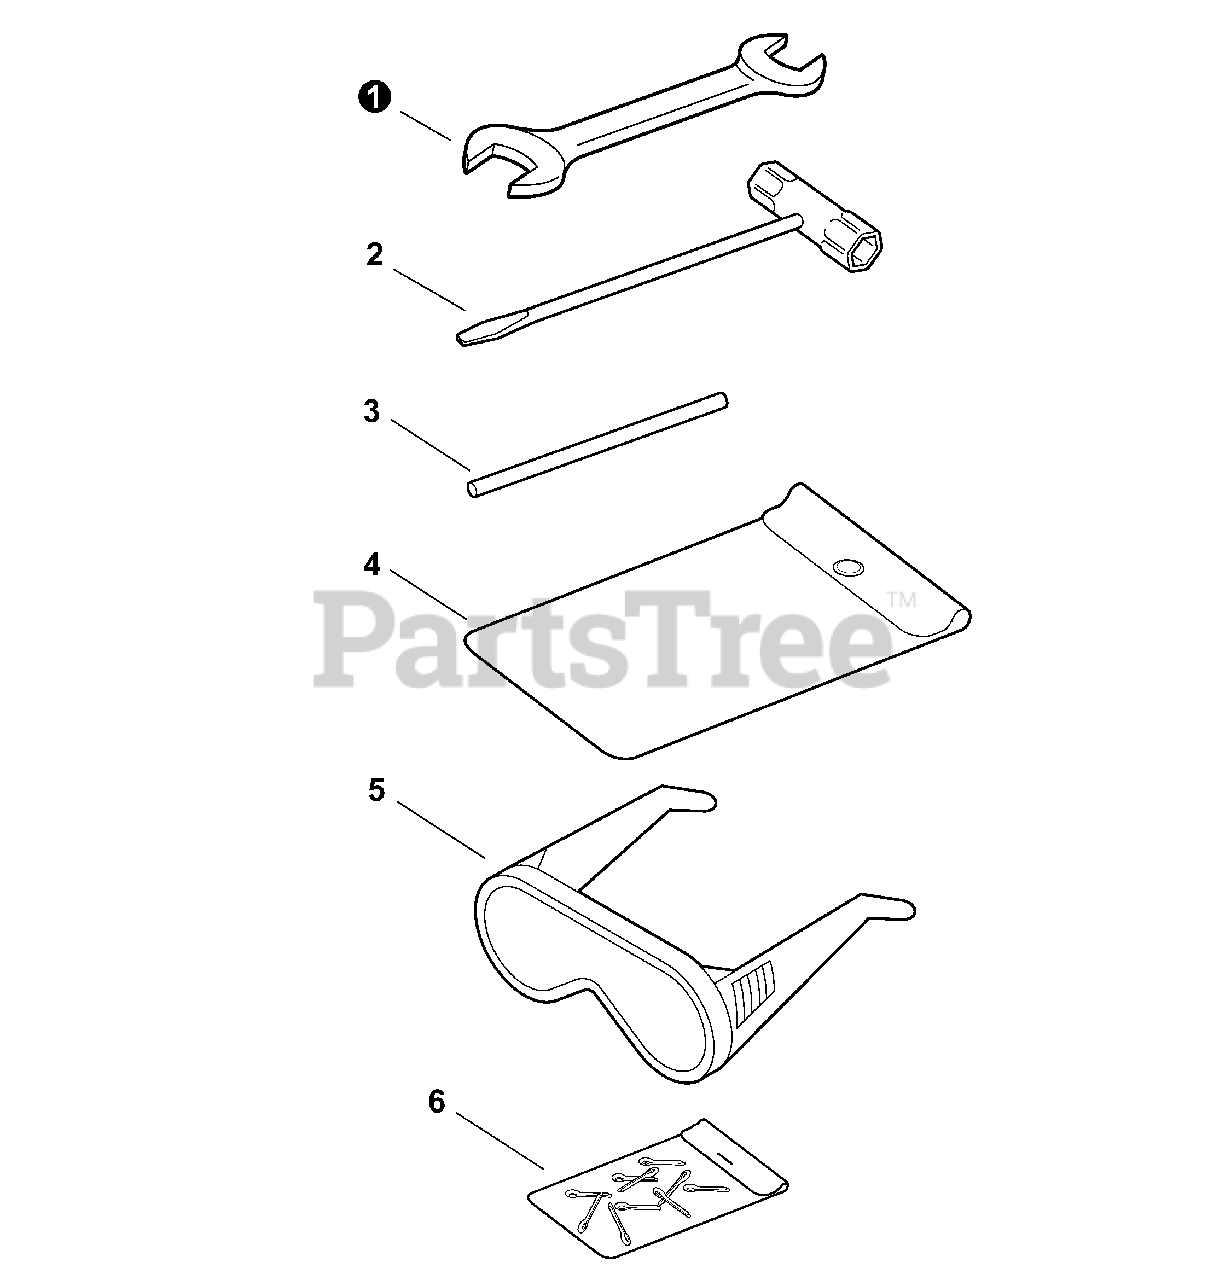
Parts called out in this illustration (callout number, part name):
1	SPANNER - 8×10mm
2	T-WRENCH - 17×19mm
3	ROD, LOCKING - 5×120mm
4	BAG,TOOL
5	GOGGLES
6	PIN, SPLIT 2×22
